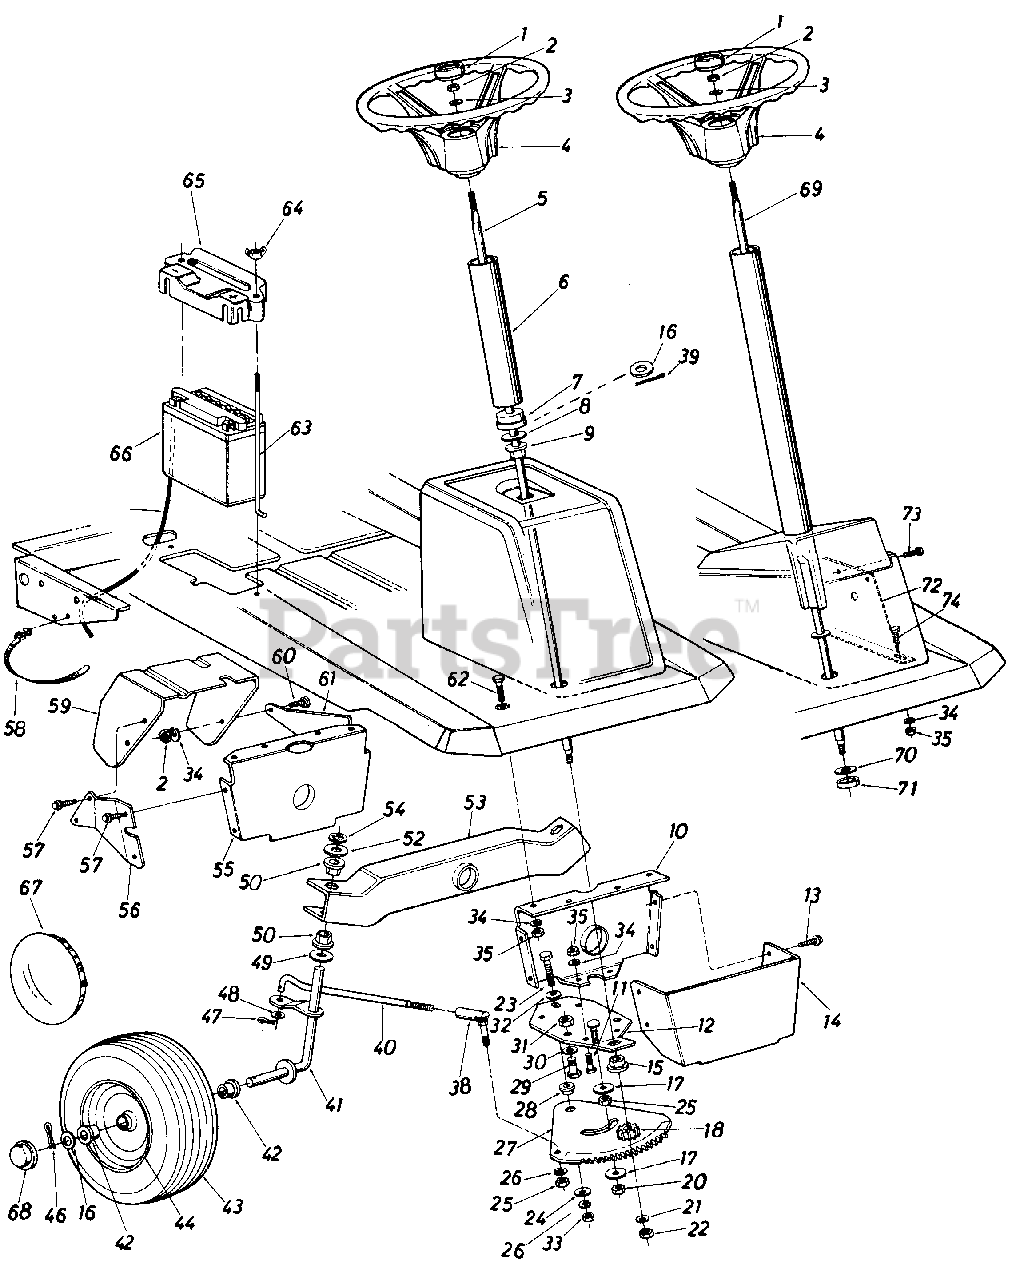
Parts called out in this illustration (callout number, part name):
1	Steering Wheel Cap
2	Hex Nut 5/16-24 Thd.
3	Bell-Wash. .345" I.D. x .88" O.D.
4	Steering Wheel Ass'y.
5	Steering Shaft
8	Fl-Wash. .640" I.D. x 1.25" O.D.
9	Hex Flange Bearing
10	Pivot Bar Bracket
12	Steering Gear Support Brkt.
13	Hex Wash. Hd. AB-Tap Scr. 1/4 x .62" Lg.
16	Fl-Wash. .640" I.D. x 1.62" O.D.
17	Fl-Washer 3/8" I.D. x 1.37" O.D.
18	Steering Pinion Gear
20	Hex L-Nut 3/8-24
21	Fl-Wash. .34" I.D. x .68" O.D.
22	Hex Nut 5/16-24 Thd.
23	Hex Bolt 3/8-24 x 1.25" Lg. (Grade 5)
24	Fl-Wash. .385" I.D. x 1.38"
25	Hex Nut 3/8-24 Thd.
26	L-Wash. 3/8" I.D.
27	Steering Gear Segment
28	Shoulder Spacer .622" Dia. x .21 8
29	Hex Bolt (Nylon) 1/2-13 x .75"
30	Fl-Wash. .530" I.D. x .930"
31	Hex Nut 1/2-13 Thd.
32	Bell-Wash. .385" I.D. x .88"
33	Hex Nut 3/8 24 Thd.
34	L-Wash. 5/16" I.D.
35	Hex Nut 5/16-18 Thd.
38	Ball Joint Ass'y. 3/8-24 Thd.
39	Cotter Pin 1/8" Dia. x 1.00" Lg.
40	Steering Tie Rod
41	Front Axle Ass'y.-R.H.
42	Flange Bearing .632" I.D.
43	Front Wheel Ass'y. Comp.
44	Front Wheel Rim Only
46	Cotter Pin 1/8" Dia. x 1.25"
47	Cotter Pin 1/8" Dia. x l.OO"
48	Fl-Wash. .385" I.D. x .87"
49	Fl-Wash. .635" I.D. x 1.12"
50	Hex Flange Bearing
52	Fl-Wash. .635" I.D. x 1.12"
53	Pivot Bar Ass'y.
54	Speed Nut 5/8" I.D.
55	Pivot Bar Bracket
56	Bracket Reinforcement-R.H.
57	Hex Wash. Hd. AB-Tap Scr. 1/4 x .62" Lg.
58	Cable Tie
59	Clutch-Brake Pedal Ass'y.
60	Hex Bolt 5/16-18 x .75" Lg.
61	Bracket Reinforcement-L.H.
62	Hex Bolt 5/16-18 x .75n Lg.
63	Battery Hold Down Rod
64	Wing Nut Solid 1/4-20 Thd.
65	Battery Hold Down Cover
66	12V Battery
67	Chrome Hub Cap
68	Plastic Hub Cap
69	Steering Shaft Ass'y.
70	Fl-Wash. .62" I.D. x 1.25" O.D.
71	Spacer (Plastic)
74	Hex Bolt 5/16-18 x 2.00n Lg.
